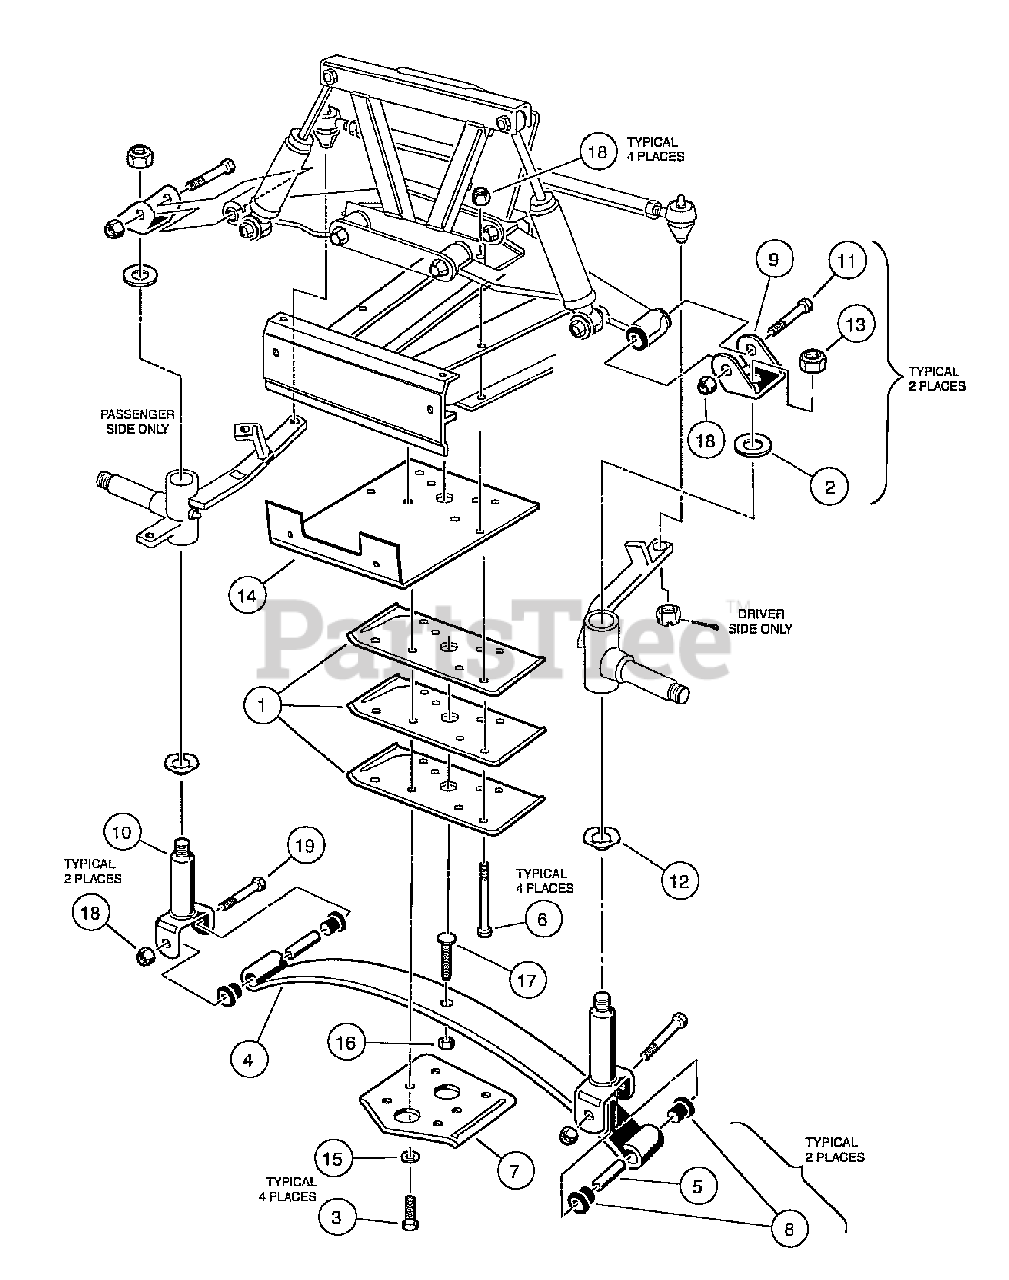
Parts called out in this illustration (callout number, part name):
1	Plate, Spring Mount
2	Bearing, Thrust
3	Bolt, 3/8-16 X 2.00 Hex Head
4	Spring, Front Leaf
5	Bushing, Steel
6	Screw, 3/8-16 X 5.00 Hex-Head Cap
7	Plate, Front Spring Retainer
8	Bushing, Urethane
9	Clevis, Delta Upper
10	King Pin Assembly
11	Screw, 3/8-16 X 2.75 Hx Hd Cap
12	Washer, 1.125 Od Wave
13	Locknut, 1/2-20 Nylon Insert
14	Support, Brush Guard
15	Washer, 3/8 Split Lock
16	Nut, 3/8-16 Hex
17	Screw, Eccentric Adjustment
18	Locknut, 3/8-16 Hex
19	Screw, 3/8-16 X 3.375 Hex Cap
